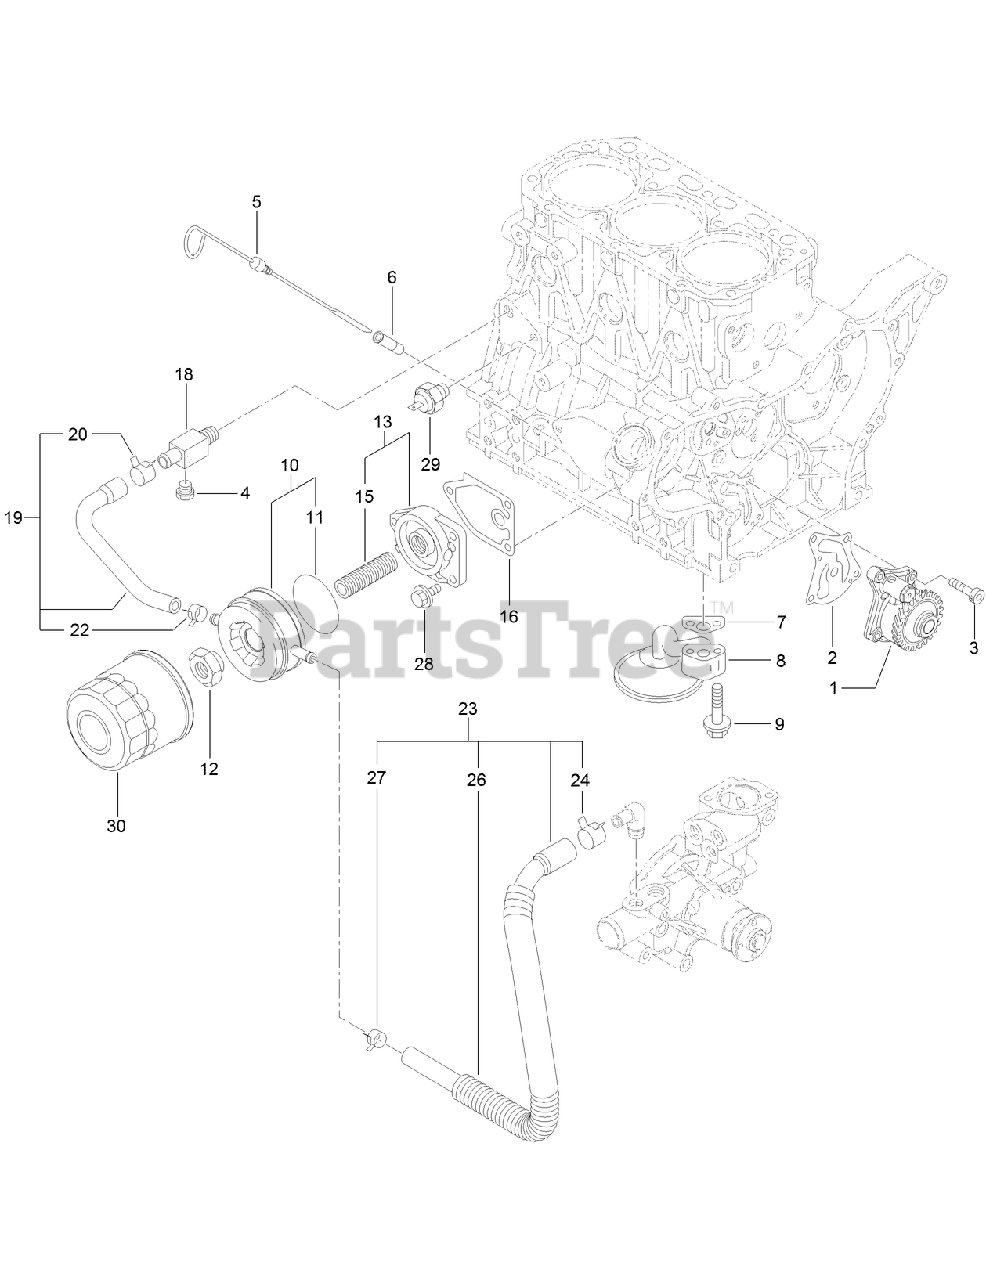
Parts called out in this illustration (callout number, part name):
1	OIL PUMP ASM
2	GASKET
4	PLUG-DRAIN
5	DIPSTICK
6	GUIDE-DIPSTICK
7	GASKET
8	PIPE ASM
10	COOLER ASM
11	O-RING
12	NUT-COOLER, OIL
13	BRACKET ASM
16	GASKET
19	PIPE ASM
22	CLAMP-HOSE
23	PIPE ASM
27	CLAMP-HOSE
29	SWITCH-OIL
30	FILTER-ENGINE
